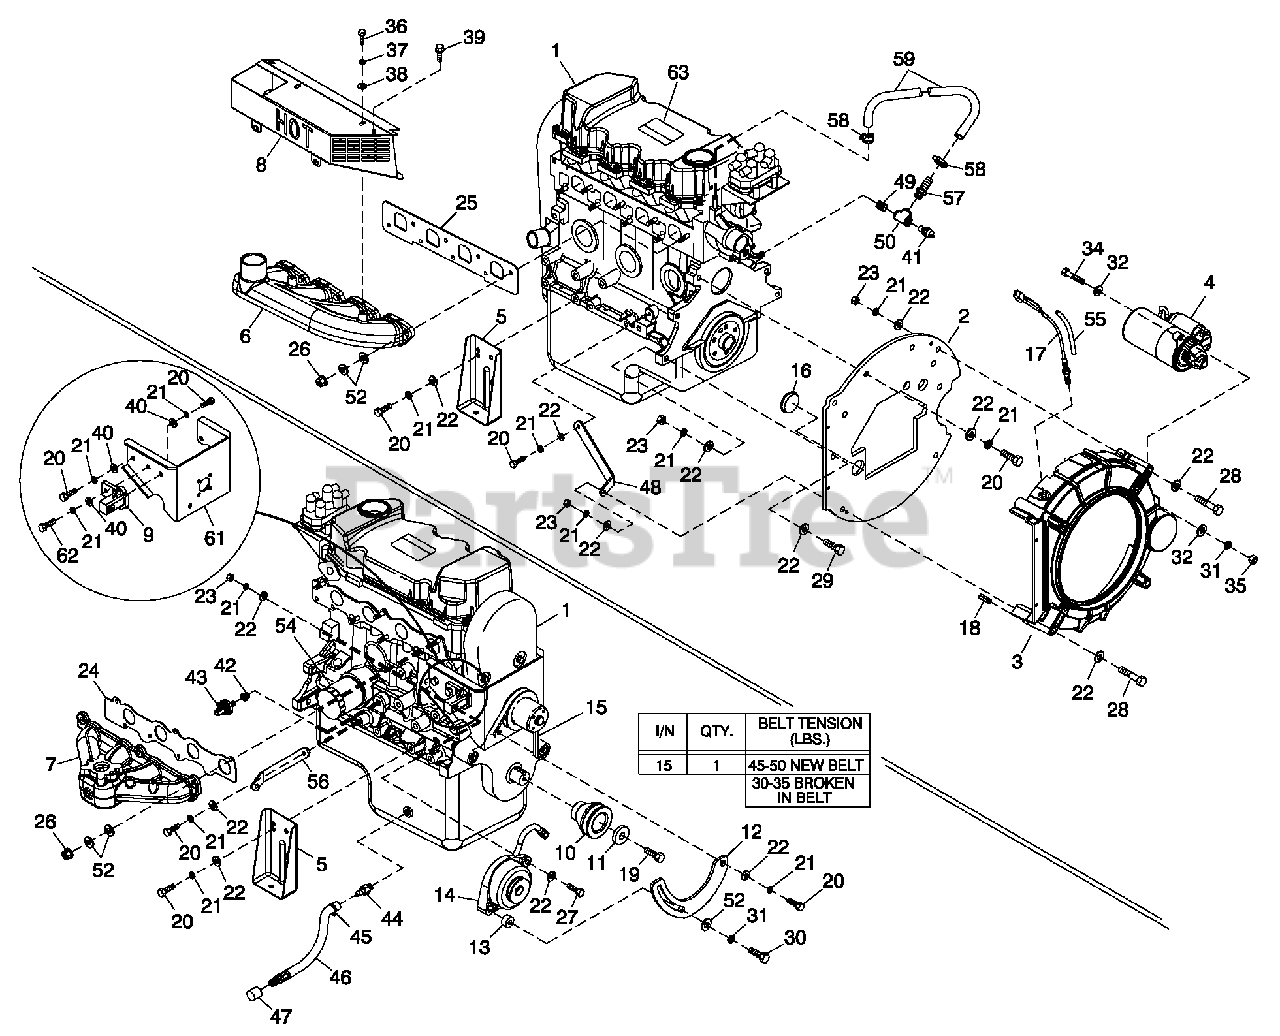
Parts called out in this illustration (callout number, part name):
1	ENGINE GENERAC1.6L NG
2	ENGINE PLATE 1.6L (TO BE USED WITH PLATE SPACER P/N 0G2070.)
3	HOUSING BLOWER MACHINED 1.6L
4	STARTER 12 VOLT
5	ENGINE MOUNTING FOOT STA MPING
6	EXHAUST MANIFOLD 1.6L MACHINED
7	INTAKE MANIFOLD MACHINED 1.6L
8	SHIELD 1.6L EXHAUST HEAT
9	DC ALTERNATOR ADAPTER MACHINED
10	PULLEY CRANKSHAFT MACHINED (3600RP M)
11	WASHER PULLEY
12	BRACKET TENSIONER DC ALT
13	SPACER ALTERNATOR
14	DC ALTERNATR HAN-KOK
15	V-BELT 3/8 X 30.6 (3600RP M)
16	CAP, 1.5" HOLE SHALLOW
17	ASSY MAGPICKUP(3/8-24 MALE)
18	PIN SPRING 1/4 X 3/4
19	SCREW HHC M12-1.5 X 40 G10.9
20	SCREW HHC M10-1.5 X 25 G10.9
21	WASHER LOCK M10
22	WASHER FLAT 3/8- M10ZINC
23	NUTHEXM10-1.5 CLASS 10 ZINC
24	GASKET INTAKE MANIFOLD 1.6L
25	GASKET EXHAUST MANIFOLD 1.6L
26	NUT TOP LOCK FL M8-1.25
27	SCREW HHC M10-1.5X 70 G8.8
28	SCREW HHC M10-1.5X 110 G10.9
29	SCREW HHC M10-1.5 X 40 G10.9
30	SCREW HHC M8-1.25X 35 G8.8
31	WASHER LOCK M8-5/16
32	WASHER FLAT 5/16- M8ZINC
33	TIE WRAP UL 7.4" X .19" BLK
34	SCREW HHC M8-1.25X 40 G8.8
35	NUT HEX M8-1.25 G8 CLEAR ZINC
36	SCREW HHC 1/4-20 X 1/2 G5
37	WASHER LOCK M6-1/4
38	WASHER FLAT 1/4- M6ZINC
39	SCREW HHTT M6-1.0 X 12 ZINC
40	WASHER FLAT M10 HEAVY DUTY
41	SWITCH HI-TE MP 245 D X 3/8 NPT
42	BSHG RDCR HEX 1/4 TO 1/8
43	SWITCH OIL PRESSURE 10PSI2POL
44	ADAPTER DRAIN OIL
45	CLAMP HOSE - OIL DRAIN
46	HOSE OIL DRAIN ASSY 21"
47	CAP HEX 1/4 NPT BRASS
48	STRUT LH 1.6L ENG ADAPT PLATE
49	NIPPLE PIPE 3/8 NPT X 1-1/2
50	PIPE TEE 3/8 NPT
51	SCREW HWHTF M6-1.0X16
52	WASHER FLAT .34 ID X.75 OD
54	OIL FILTER 1.6L
55	CONDUIT FLEX .25"ID (6" LG)
56	STRUT RH 1.6L ENG ADAPT PLATE
57	BARBED STR 3/8 NPT X 3/8
58	CLAMP HOSE .38-.87
59	HOSE 3/8 ID LOW PRES OIL/WATER (11" LG)
61	BRACKET FAN ALT ADAPTER 1.6L
62	SCREW HHC M10-1.5X 35 G8.8
63	DECAL E MISSION CTRL INFO 1.6L
